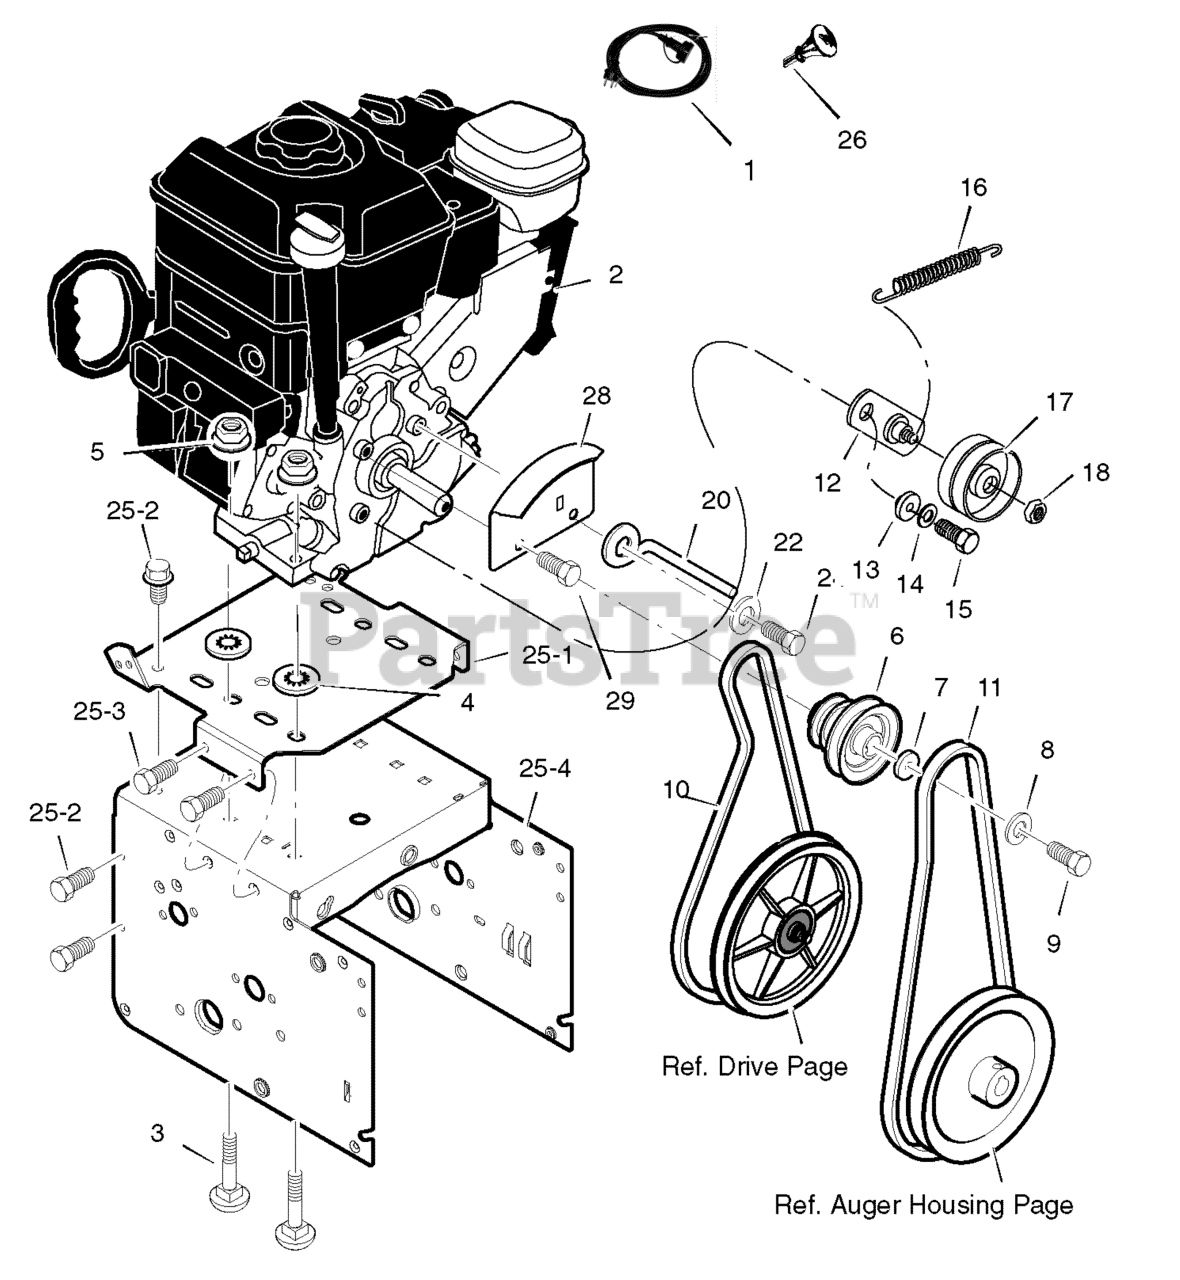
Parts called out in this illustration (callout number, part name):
1	CORD, STARTER
2	ENGINE
3	BOLT, CARRIAGE 5/16-18
4	RETAINER, PUSH
5	NUT 5/16-18
6	PULLEY, ENGINE
8	WASHER .38ID
9	SCREW, 3/8-24 x 1.00
10	BELT, DRIVE V 3L
11	BELT, AUGER V 4L
12	BRACKET ASSEMBLY, IDLER
13	BUSHING, IDLER BRACKET
14	WASHER, SPLIT
15	SCREW 5/16-24 X 0.75
16	SPRING, IDLER TRACTION DRIVE
17	PULLEY, IDLER
18	NUT, JAM 3/8-16
20	GUIDE, BELT
22	WASHER .31X.58X.08
24	SCREW, 5/16-24 x 0.75
25-1	PLATE, ENGINE MOUNT
25-2	SCREW, TAP 1/4-20 X .63
25-3	SCREW, TAP 5/16-18 X .50
25-4	FRAME, MOTOR BOX
26	KEY, BRIGGS ENGINE
28	SHEILD, BRIGGS ENGINE
